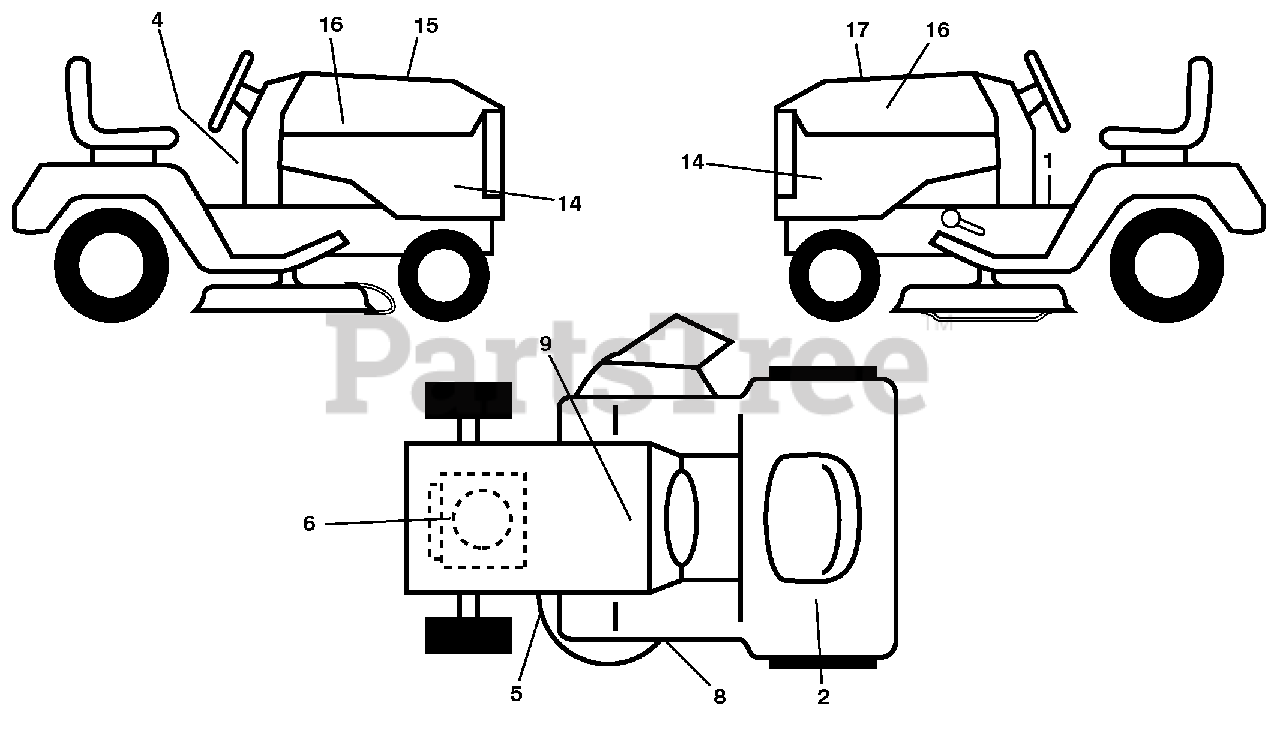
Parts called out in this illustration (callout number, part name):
1	Decal, Warning
2	Decal, Warn Reserve Fuel
4	Decal Warning Spark Arrestor
5	Decal, Caution
6	Decal, Eng.
8	Decal, Mower Sch.
9	Decal, Battery Dnge/Poi
14	Decal, Panel Side
15	Decal, Cust. Resp.
16	Decal, Hood Logo
17	Decal, Replacement
